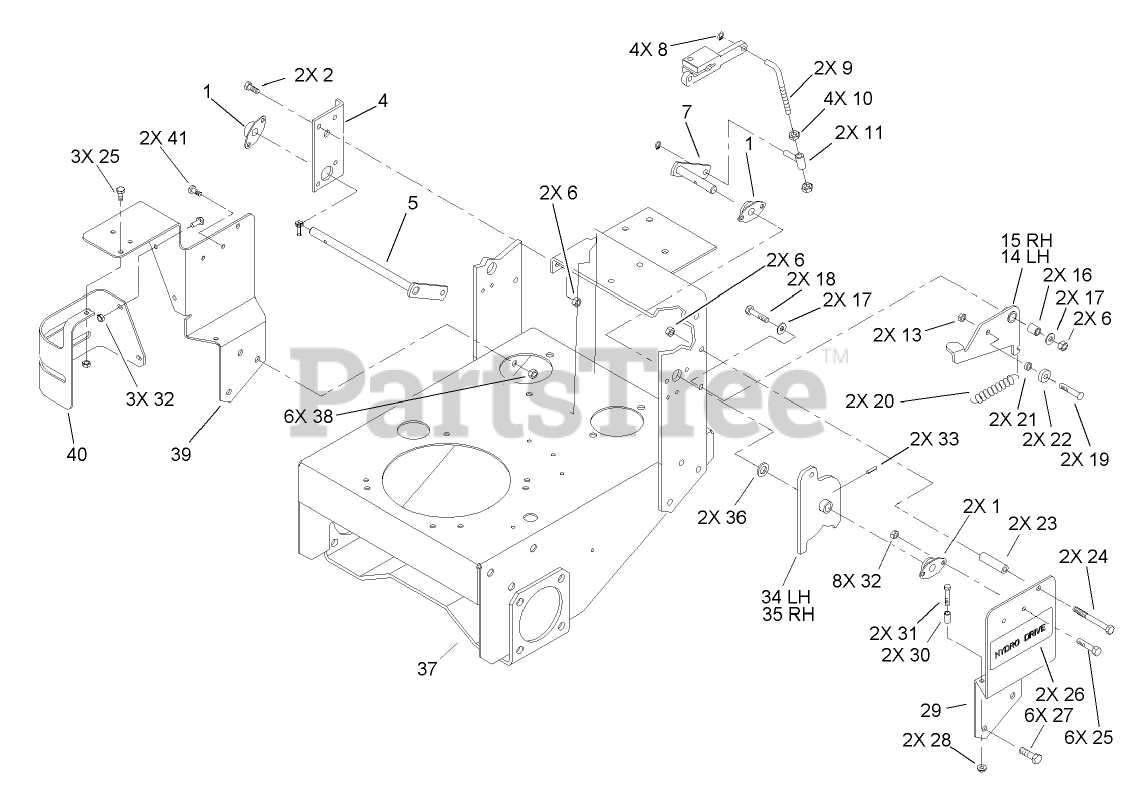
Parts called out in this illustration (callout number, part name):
1	SIDE FLANGE BEARING ASM
2	SCREW-HH
4	BRACKET-BUSHING
5	LEVER-PIVOT, RH
6	NUT-LOCK, NI
7	LEVER-PIVOT, LH
8	RING-GRIP
9	ROD-LINK
10	NUT-JAM
11	SLEEVE
13	NUT-LOCK, NI
14	ARM-DETENT, LH
15	ARM-DETENT, RH
16	BUSHING-ARM, DETENT
17	WASHER-PLAIN
18	SCREW-HH
19	SCREW-HSBH
20	SPRING-DETENT
21	SPACER-BEARING
22	BEARING-BALL
23	STOP-REVERSE
24	SCREW-HH
25	SCREW-HH
26	DECAL-HYDRO
27	SCREW-HH
28	NUT-LOCK, HHF
29	BRACKET-PIVOT, LH
30	SPACER-TUBULAR
31	SCREW-HH
32	NUT-LOCK, NI
33	PIN-ROLL, SLOTTED
34	ARM-PIVOT, LH
35	ARM-PIVOT, RH
36	WASHER-THRUST
37	Frame ASM
38	NUT-LOCK, NI
39	BRACKET-PIVOT, RH
40	GUARD-FILTER
41	SCREW-HH
